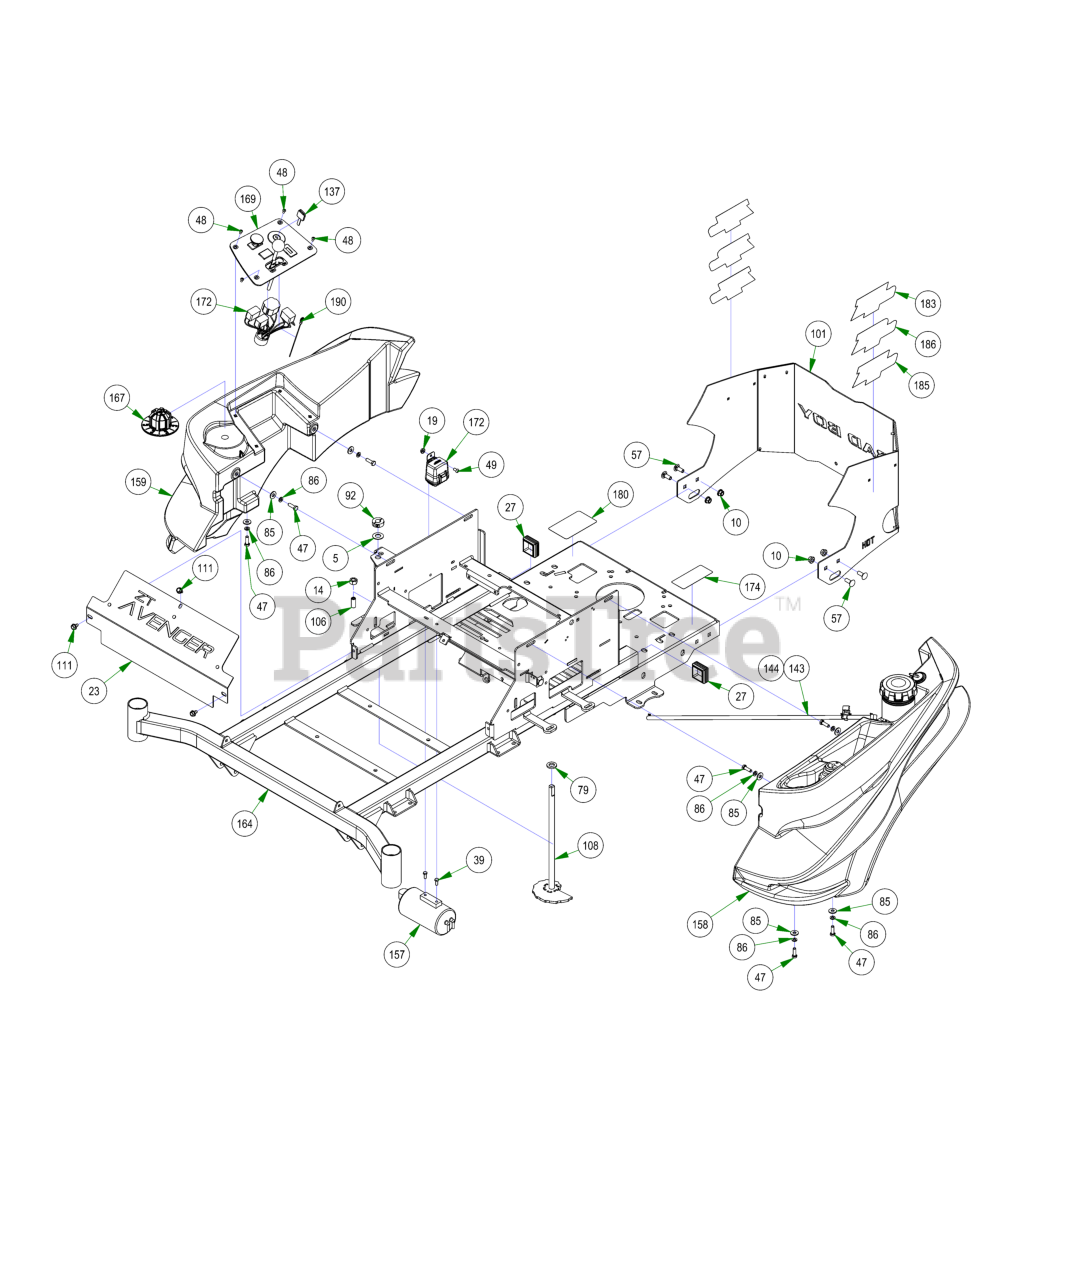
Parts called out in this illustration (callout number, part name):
5	.625 ID x 1.250 OD x .062 THK F/W Nylon
10	3/8-16 NYLON INSERT FLANGE LOCKNUT (GR.F) ZINC
14	1/2-13 HEX NUT ZINC
19	1/4-20 HEX SERRATED FLANGE NUT HARD/ZINC
23	2023 ZT Avenger Cooler Cover Assembly
27	2X2 Frame Plug
39	M6-1.0 X 16MM DIN 933 HEX TAP BOLT (CL 8.8) ZINC
47	5/16-18 X 1 HEX CAP SCREW (GR.5) ZINC
48	10-32 X 3/8 BUTTON SOCKET CAP SCREW 18-8 STAINLESS STEEL
49	1/4-20 X 1/2 BUTTON SOCKET CAP SCREW 18-8 STAINLESS STEEL
57	3/8-16 X 1 CARRIAGE BOLT (GR.5) ZINC
79	.635 ID X 1.120 OD X .140 THICK FLAT WASHER NYLON
85	5/16 USS FLAT WASHER (7/8 OD) ZINC
86	5/16 SPLIT LOCKWASHER ZINC
92	5/8" Split Collar
101	2022 ZT Avenger Rear Cover Assembly
106	Dial Rod Plunger
108	ZT Deck Height Bar Assembly
111	5/16-18 X 1/2 HWH unslot (F) tcs zinc
137	Ignition Key
143	15" Fuel Line Assembly
143.3	Fuel Line 4" Section with Clamps
143.3.1	1/4 Fuel Hose Clamp
143.3.2	4" 1/4 Fuel Line
144	37" Fuel Line Assembly
144.3	Fuel Line 4" Section with Clamps
144.3.1	1/4 Fuel Hose Clamp
144.3.2	4" 1/4 Fuel Line
157	ZT/Mav EPA Cannister Assy
158	Left Fuel Tank
158.3	Fuel Gauge w/Grommet
158.4	Rollover Valve W/Grommet
158.5	Pick-Up Grommet
159	Right Side Console
164	2023 MZ-Avenger 54-60 Frame - Painted
167	MZ/ZT Deck Height Dial
169	2023 Control Panel Assembly
172	Wiring Harness
174	2023 EPA Build Date Punch Decal
180	Pump Belt Route Decal-Pump Plate
183	725cc ZT Decal
185	ZT Avenger 724cc Back Plate Decal
186	ZT Avenger 726cc Back Plate Decal
190	2017 MZ/ZT/MAV Tach Wire Assy
